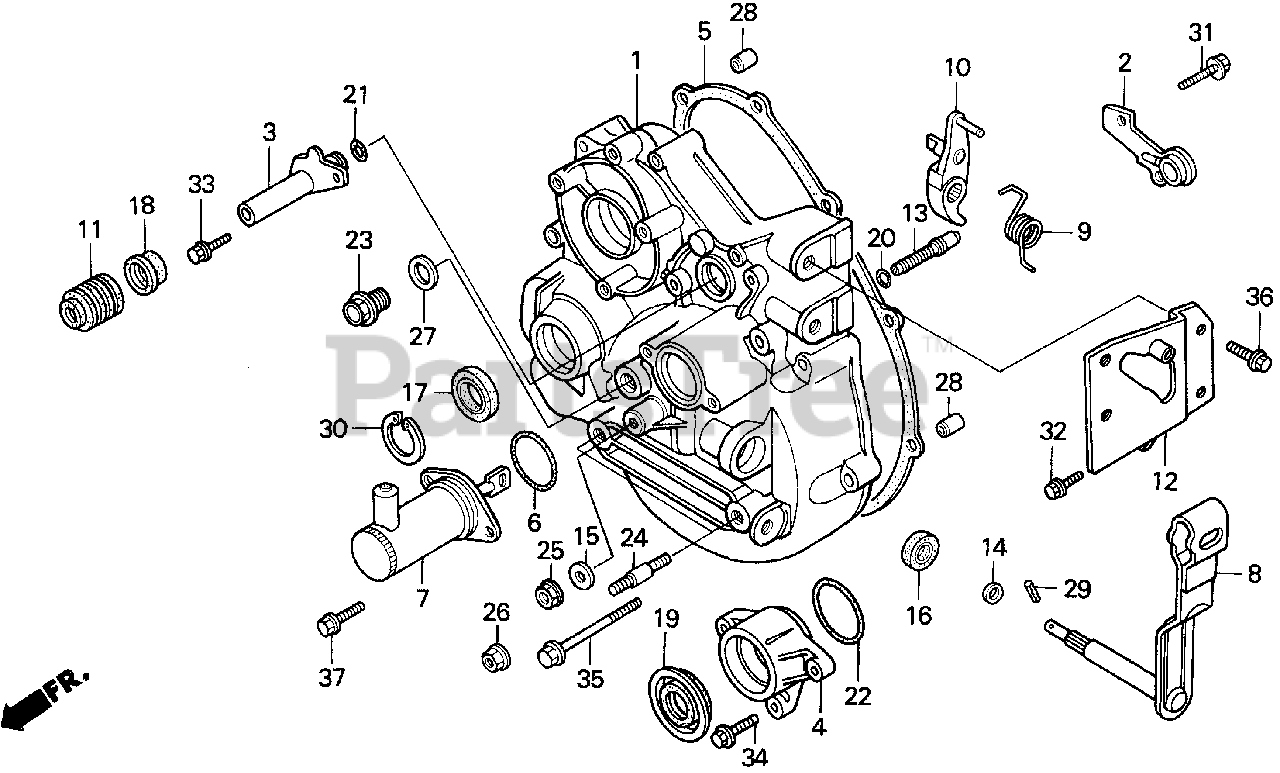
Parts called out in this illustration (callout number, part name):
1	COVER, CLUTCH
2	PLATE, OIL GUIDE
3	HOLDER, SHIFT PIECE SHAFT
5	GASKET, CLUTCH COVER
6	O-RING (37.5X2)
7	DAMPER ASSY., CLUTCH
8	LEVER, CLUTCH
9	SPRING, CLUTCH LEVER
10	CAM, CLUTCH LIFTER
11	BOOT, SHIFT SHAFT
12	BRACKET, CHANGE LEVER HOLDER
13	BOLT, ADJUSTING (8MM)
14	WASHER, THRUST (10X16)
15	WASHER (8MM)
16	OIL SEAL (14X24X6) (ARAI)
17	OIL SEAL (22X34X7)
18	OIL SEAL (14X24X11.5)
20	O-RING (6.8X1.9)
21	O-RING (21.5X1.5)
23	BOLT, DRAIN PLUG (14MM)
24	BOLT, STUD (10X25)
25	NUT, FLANGE (8MM)
26	NUT, FLANGE (10MM)
27	WASHER, DRAIN PLUG (14MM)
28	PIN A, DOWEL (10X16)
29	PIN, SPRING (3X16)
30	CIRCLIP (INNER) (34MM)
31	BOLT, FLANGE (6X16)
32	BOLT, FLANGE (8X20)
33	BOLT, FLANGE (8X22)
35	BOLT, FLANGE (8X55)
36	BOLT, FLANGE (10X25)
37	BOLT, FLANGE (6X16)
